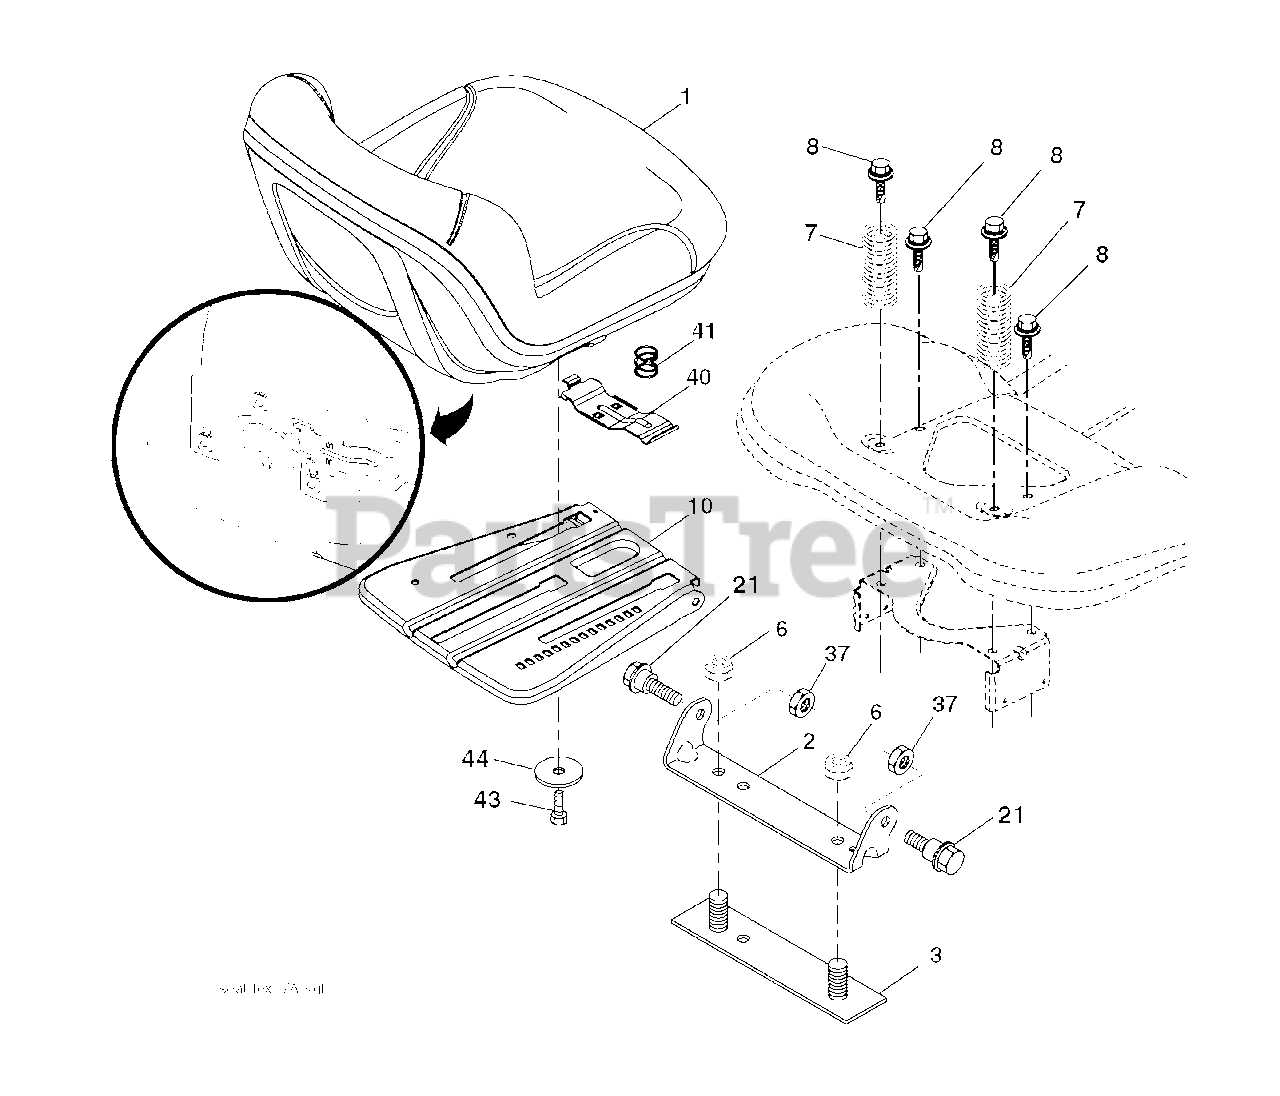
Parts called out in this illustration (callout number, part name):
1	SEAT.TG150.BLK.NLOGO.
2	BRKT.PIVOT.FENDER
6	NUT
7	SPRING COMPRESSION
8	BOLT, 5/16-18 X 1 3/4
10	PAN.ASM.SEAT.3PT
21	BOLT.SHOULDER.5/16-18
37	NUT.71038.31-18.HEX.NYLOCK
40	HANDLE.SLIDE.SEAT.TEX.BLACK
41	SPRING.LATCH.SEAT.TEX
44	WASHER 13/32 X 2-3/8 X 12GA
